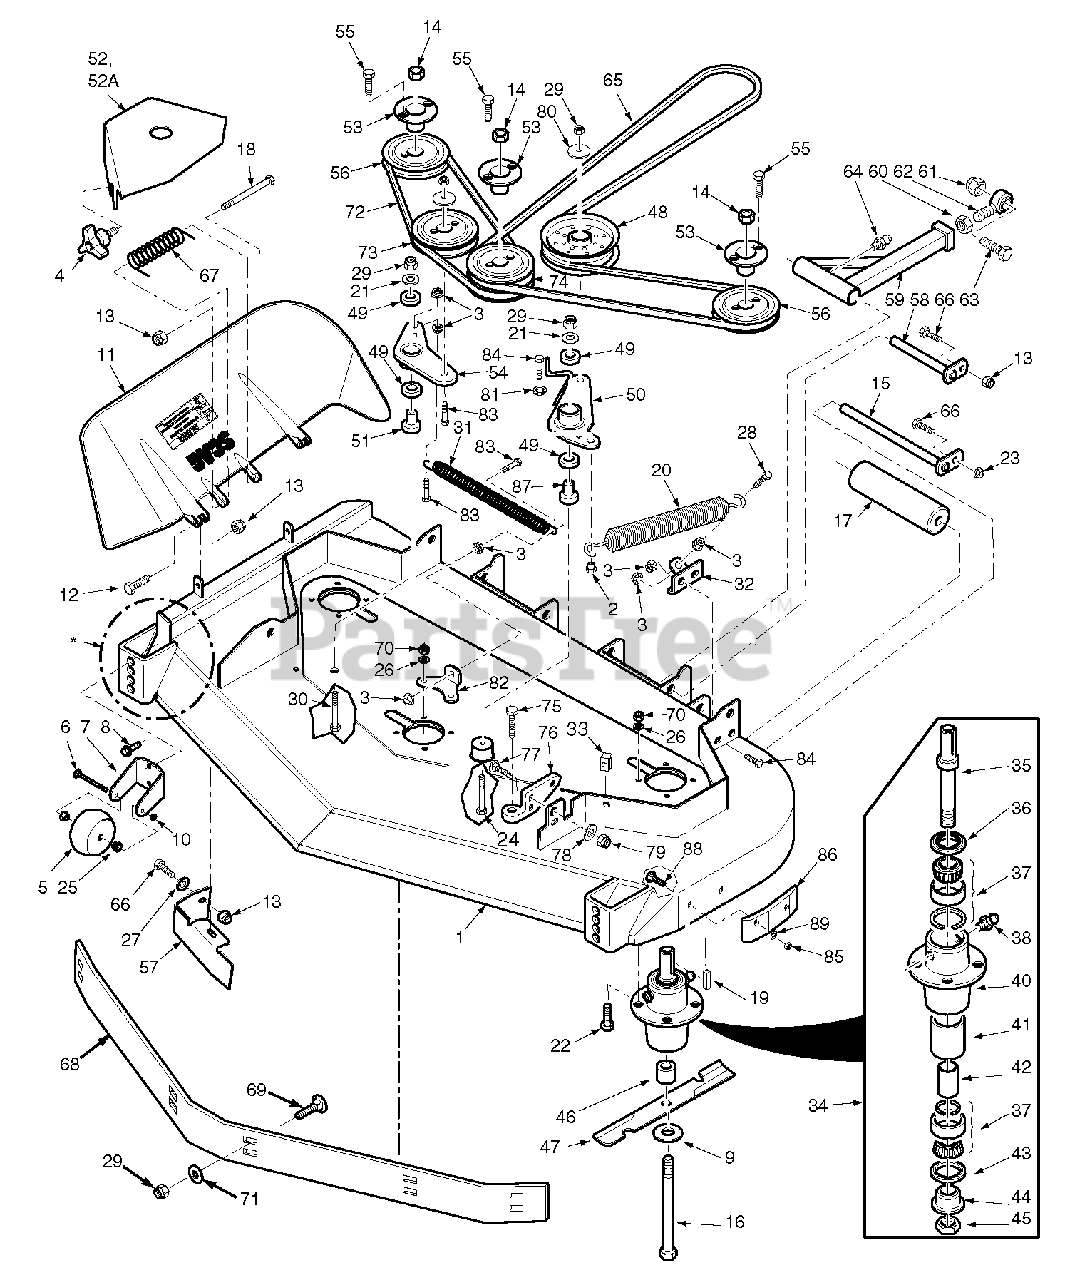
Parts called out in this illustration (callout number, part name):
1	Cutter Deck Velocity Plus
2	Boss, Spring Anchor
3	Nut, 3/8-16 Serrated Flange
4	Wing Nut, 3/8-16
5	Anti-Scalp Wheel
6	Bolt, Carriage 3/8-16 x 4"
7	Bracket, Anti-Scalp Wheel
8	Bolt, Serrated Flange 3/8-16 x 1"
9	Flatwasher, 5/8" Hardened
10	Locknut, 3/8-16 Center Lock
11	Discharge Chute
12	Bolt, Hex Head 5/16-18 x 1-1/2", Rear
12	Bolt, Hex Head 5/16-18 x 1-3/4", Front
13	Nut, Elastic Stop 5/16-18
14	Nut, 5/8-11 UNC
15	Shaft, Roller
16	Bolt, Hex Head 5/8-11 x 9-1/2"
17	Roller, Rear
18	Bolt, Hex Head 5/16-18 x 4-3/4"
19	Key, 1/4 x 1/4 x 2"
20	Spring, Idler LH
21	Flatwasher, 3/8"
22	Bolt, Hex Head 5/16-18 x 1-3/4" Gr. 8
23	Nut, Serrated Flange 5/16-18
24	Bolt, Hex Head 3/8-16 x 3-3/4"
25	Bushing, .376 ID Oilite
26	Lockwasher 5/16"
27	Flatwasher 5/16"
28	Bolt, Hex Head 3/8-16 x 1-1/2" Gr. 8
29	Nut, Elastic Stop 3/8-16
30	Bolt, Hex Head 3/8-16 x 2-1/2"
31	Spring, Idler RH
32	Bracket, Spring Anchor LH 48V
32	Bracket, Spring Anchor LH 52V
33	U-Nut, 3/8-16
34	Spindle Assembly
35	Shaft, Spindle
36	Seal Upper
37	Bearing Assembly
38	Grease Fitting
39	Valve, Grease Relief
40	Housing, Spindle
41	Spacer, Outside
42	Spacer, Inside
43	Seal, Lower
44	Bushing, Bottom
45	Nut, Special 1-1/16 - 18
46	Spacer, Spindle
47	Cutter Blade 16.5"
47	Cutter Blade 18"
48	Pulley, Idler 5" Dia.
49	Bearing
50	Idler Arm Assy.
51	Idler Pivot
52	Belt Cover (48V)
52	Belt Cover (52V)
53	Hub, Tapered 1-1/8" Bore
54	Idler Arm
55	Bolt, Hex Head 1/4-20 x 1"
56	Pulley 4.75"
56	Pulley 5.35"
57	Turbo Baffle, Bolt On
58	Push Arm Shaft
59	Push Arm
60	Nut, 5/8-18 UNF
61	Nut, Elastic Stop 5/8-11
62	Rod End, 5/8 Male RH Thread
63	Bolt, Hex Head 5/8-11 x 4-1/2"
64	Grease Fitting, 90 Degree
65	Belt, Cutter Deck Drive (48V)
65	Belt, Cutter Deck Drive (52V)
66	Bolt, Hex Head 5/16-18 x 1"
67	Spring, Discharge Chute
68	Baffle Custom-Cut, 48V (7-Position)
68	Baffle Custom-Cut, 52V (7-Position)
69	Bolt, Carriage 3/8-16 x 1"
70	Nut, Elastic Stop 5/16-18
71	Flatwasher 3/8"
72	Belt, RH Cutter Deck
73	Pulley, Idler 5" Dia.
74	Pulley, Double Groove
75	Bolt, Special
76	Lever Assy., Deck Level
77	Bolt, Carriage 7/16-14 x 1-1/4"
78	Flatwasher, 7/16-.500 x 1.25 x .083"
79	Nut, Elastic Stop 7/16-14
80	Dust Shield
81	Lockwasher 3/8"
82	Bracket, Spring Anchor RH
83	Bolt, Hex Head 3/8-16 x 1-1/2" Gr. 8
84	Bolt, Hex Head 3/8-16 x 1"
85	Nut, Center Lock 5/16-18
86	Wear Pad
87	Idler Pivot
88	Bolt, Carriage 5/16-18 x 3/4"
89	Flatwasher, 5/16"
